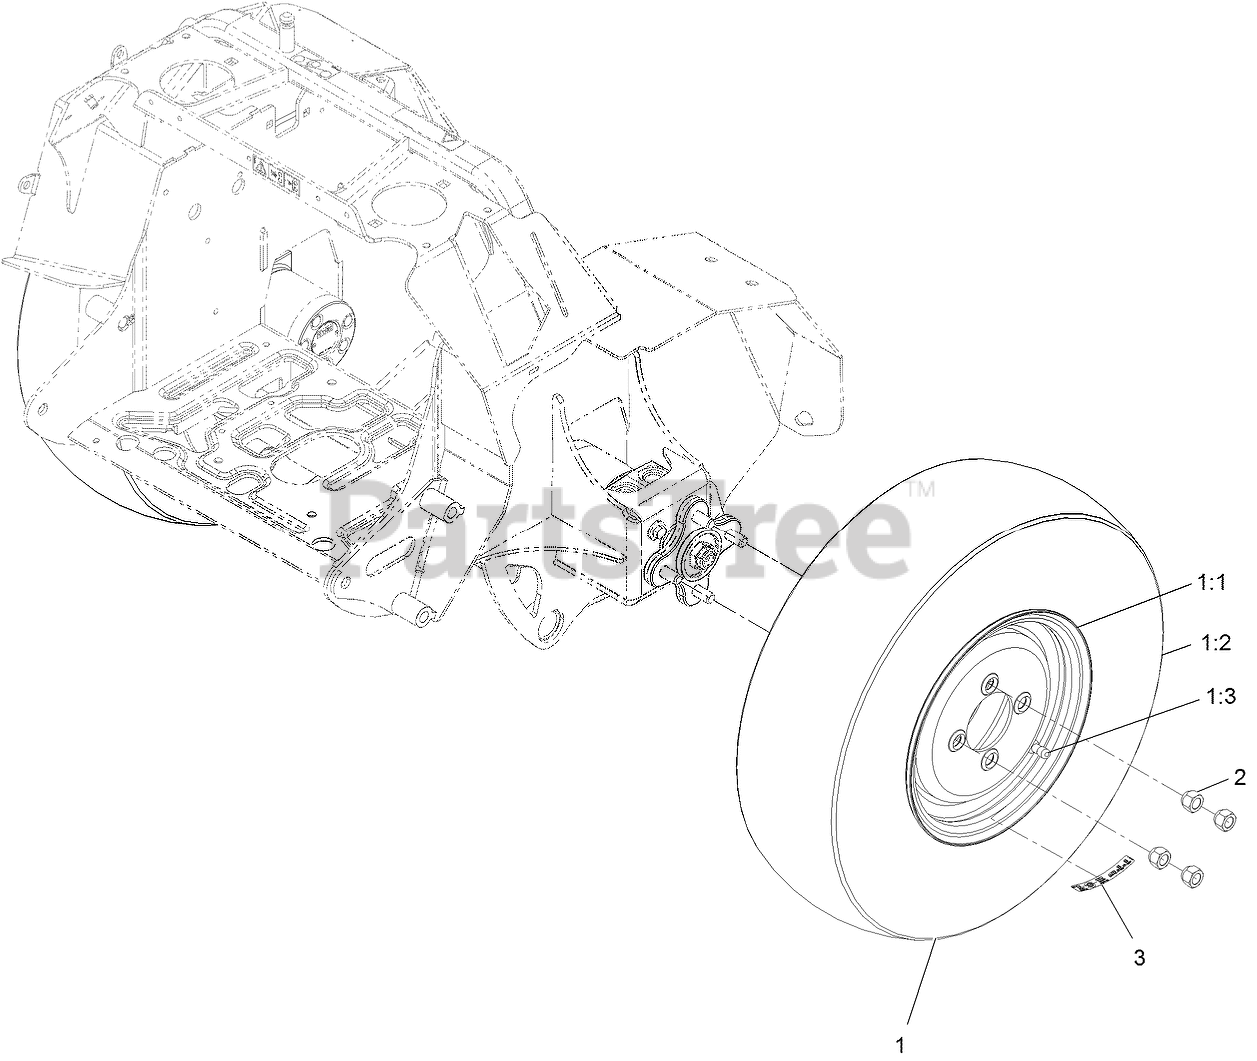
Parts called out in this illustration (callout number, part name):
1	ASM-WHL TIRE
1:1	WHEEL 10 X 5.5 WHT
1:2	TIRE 21X7.00-10
1:3	Stem-Valve
2	NUT-LUG
3	DECAL-TORQUE WHEEL LUG-HU
